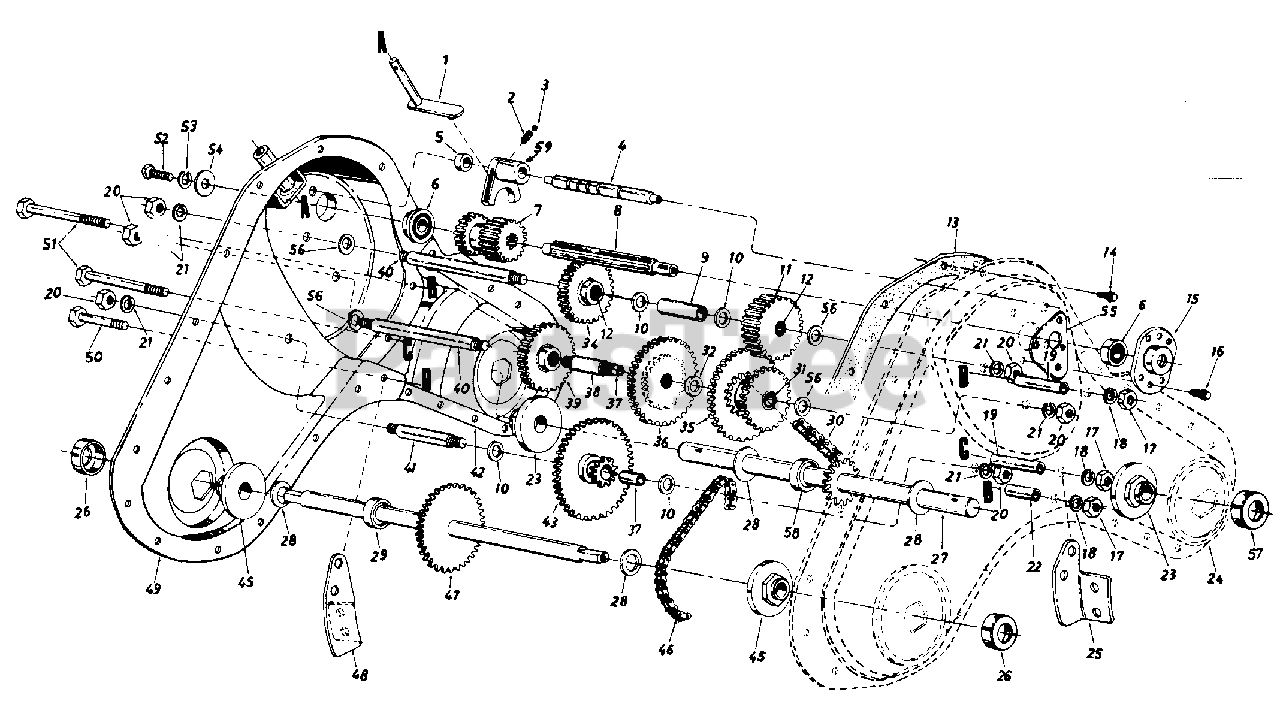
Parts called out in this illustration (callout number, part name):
1	Shifting Bracket Ass'y.
2	Compression Spring .50" Lg.
3	Ball Detent. 250" Dia.
4	Detent Shaft 1/2" Dia.
5	Spacer .505" I.D. x .88" O.D.
6	Ball Brg. .62" I.D. x 1.38"
7	Spur Gear 16T
8	Input Spline Shaft 7/8
9	Spacer .657" I.D. x 2.85" Lg.
10	Fl-Wash. .640" I.D. x 1.24"
11	Spur Gear 30T 7/8" I.D. x 1-1/4" O.D.
12	Needle Bearing 5/8" I.D.
13	Gasket-Trans. Hsg.
14	Hex Wash. S-Tap Scr. 1/4-20 x.50" Lg.
15	1-3/8" Dia. Bearing Housing
16	Hex TT-Tap Scr. 1/4-20 x .75"
17	Hex Nut 5/16-18 Thd.
18	L-Wash. 5/16" l.D.
19	Spacer 1.56" Lg.
20	Hex Nut 7/16-20 Thd.
21	Bell-Wash. .45" I.D. x 1.0"
22	Spacer 1.015" Lg.
23	Tine Shaft Brg. 1.002 x 2.50
24	Trans. Housing Ass'y.-L.H.
27	Tine Shaft Ass'y. 1.00" O.D.
28	Thrust Washer 1.030 I.D. x 1.62" O.D.
29	Spacer 1.0" I.D. x .50" Lg.
30	Chain #50 5/8 Pitch x 52 0 Links-Endless
31	Needle Bearing 5/8" I.D.
32	Fl-Wash. 5/8" I.D. x 11/4" O.D. x .150
34	Spur Gear 30T 12/16" I.D. x 1/2" W
35	30/44T Gear Ass'y. Comp.
36	Spur Gear 44T
37	Sleeve Bearing
38	Gear Hub 3/4" I.D. x 3.0" Lg.
39	Spur Gear 30T 1.0" I.D. x 1/2 W
40	Jack Shaft 5/8" Dia. x 5.
41	Jack Shaft 5/8n Dia. x 2.3
45	Wheel Brg. .752 x 2.50
46	#420 Chain 1/2 Pitch x 50 0 Links-Endless
47	Wheel Shaft Ass'y.
51	Hex Bolt 5/16-18 x 2.50
52	Hex Bolt 1/4-20 x .62" Lg.
53	L-Wash. 3/8" I.D.*
54	Fl-Wash. 1/4" I.D. x .93" O.D.
55	Gear Positioner Bracket
56	Fl-Wash. 7/16" I.D. x 1-3/8" O.D.
57	Dust Cover Ass'y. 1.0" Shaft
58	Spacer .75" I.D. x 2.0" O.D.
59	Shifting Fork
